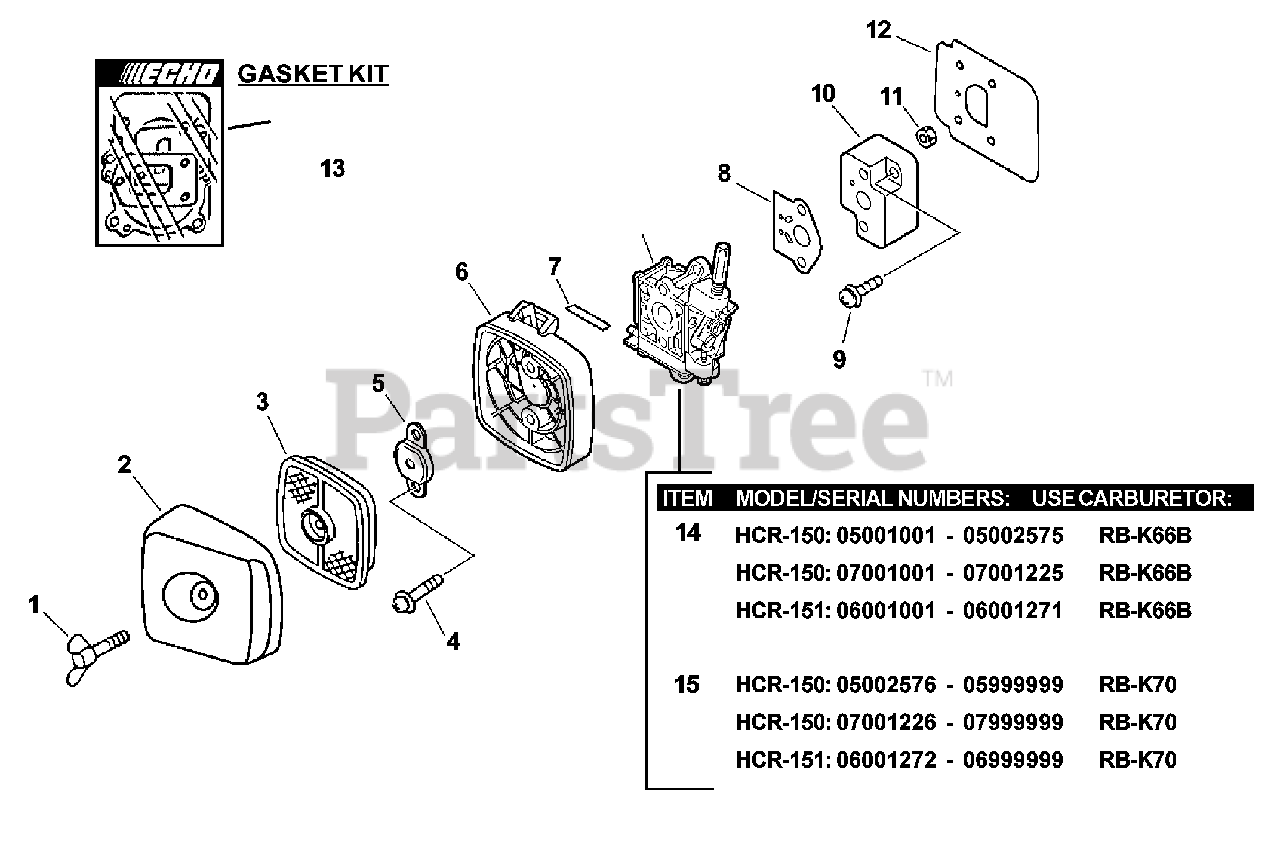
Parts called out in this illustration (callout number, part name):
1	BOLT, WING 5×20
2	COVER, AIR FILTER - GRAY
3	FILTER, AIR - SINGLE LAYER
4	SCREW 5×65
5	PLATE, PREVENT
6	CASE, AIR FILTER - GRAY
7	LABEL, CHOKE
8	GASKET, CARBURETOR
9	SCREW 5×20
10	INSULATOR, INTAKE
11	NUT M5
12	HEAT SHIELD, INTAKE
13	GASKET KIT
14	CARBURETOR - RB-K66B
15	CARBURETOR - RB-K70
